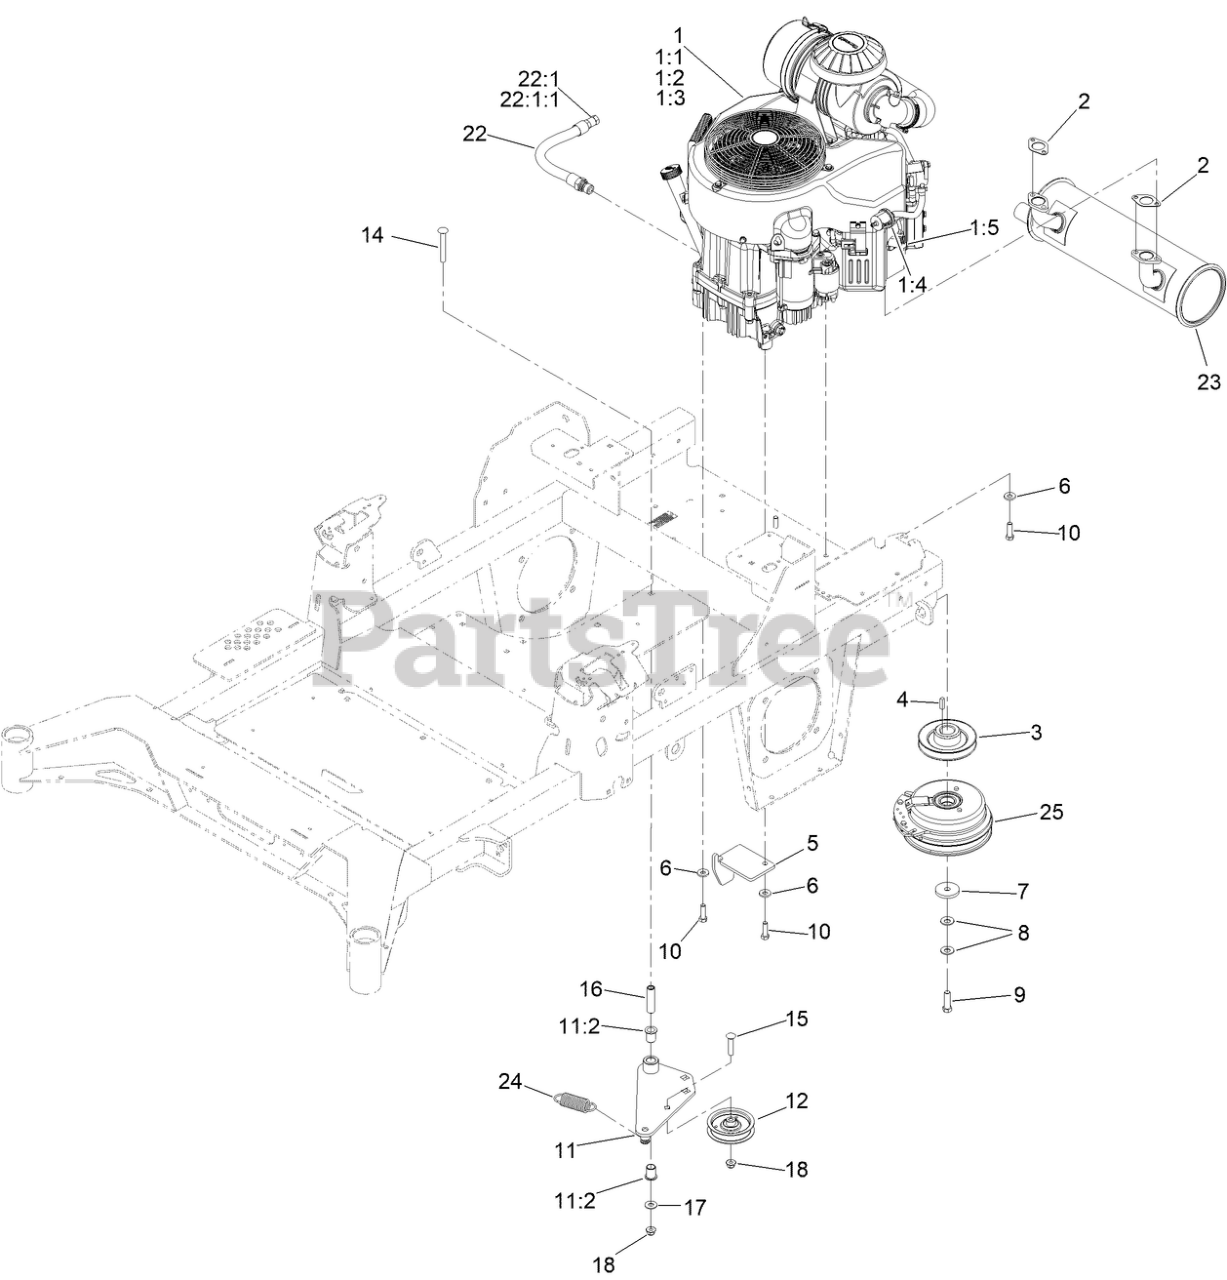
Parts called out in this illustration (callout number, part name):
1	ENGINE-KAWASAKI
1:1	FILTER-OIL KAW
1:2	ELEMENT-FILTER, AIR (OUTER)
1:3	ELEMENT-FILTER, AIR (INNER)
1:4	FILTER-FUEL
1:5	SPARK PLUG
2	GASKET-EXHAUST
3	SHEAVE, W/HUB
5	ANCHOR-CLUTCH
6	WASHER-BELLEVILLE
7	WASHER-CLUTCH
8	WASHER-SPRING
9	SCREW-HH, W/LOCTITE
10	SCREW-HH
11	IDLER ARM ASM
11:2	BUSHING-FLANGE
12	PULLEY-IDLER, FLAT
14	SCREW-CARR
15	SCREW-CARR
16	BUSHING, IDLER PIVOT
17	WASHER-FLAT
18	NUT-HF, NI
22	ENGINE OIL DRAIN HOSE ASM
22:1	PLUG-HH
22:1:1	O-RING
23	MUFFLER
24	SPRING-IDLER
